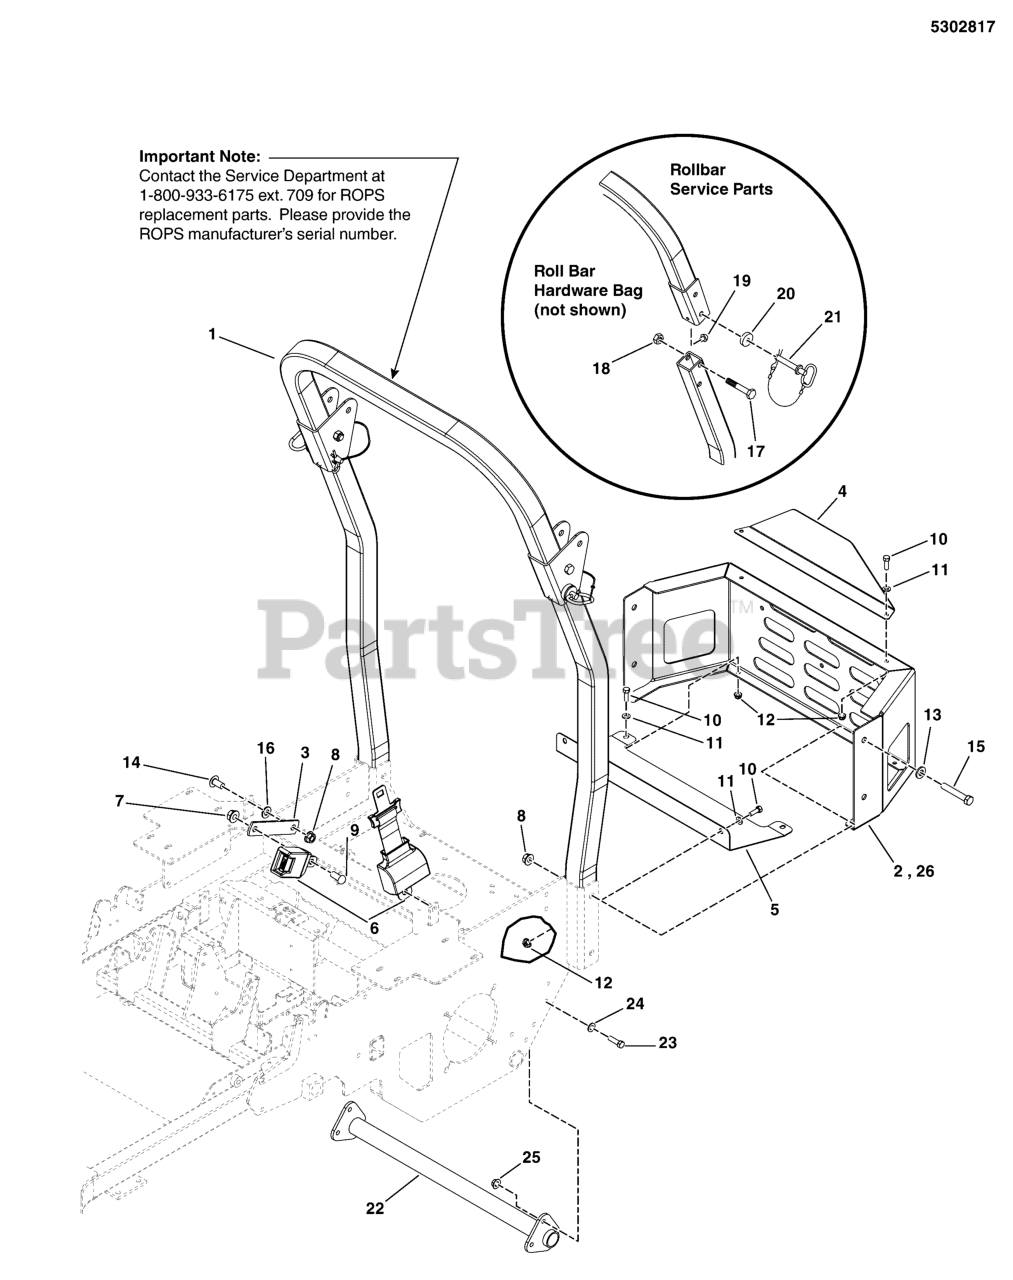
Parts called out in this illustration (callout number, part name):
1	ROPS (Call 1-800-933-6175 ext. 2193 if replacing a ROPS)
2	WELD, PLATE, BUMPER - RED
3	EXTENSION, SEAT BELT - BLK
4	PLATE, CARB. SHIELD - RED
5	PLATE, HEAT SHIELD - BLK
6	SEAT BELT, RETRACTING - ASSM
7	NUT, Hex, Nylon Lock, 1/2-20
8	NUT, Hex Flange, Nylock, 1/2-13
9	SCREW, 1/2-13 X 1.00, SHCS
10	BOLT, 5/16-18 X 3/4 GD5
11	WASHER, 5/16" SAE
12	NUT, 5/16-18 HEX NYLOCK FLANGE
13	WASHER, 1/2 SAE
14	BOLT, 1/2-20 X 1-1/4" GD5 CZ
15	BOLT, 1/2-13 X 3" GD5 CZ
16	WASHER, 1/2 GD9 YZ
17	* BOLT (SV)
18	* NUT (SV)
19	RUBBER BUMPER (SV)
20	RUBBER WASHER (SV)
21	PIN, HITCH, BLACK W/ PLASTIC LANYARD (SV)
22	WELD, BRAKE BUMPER - RED
23	BOLT, 3/8-16 X 1-1/4" GD5 CZ
24	WASHER, 3/8 SAE
25	NUT, 3/8-16 HEX SERRATED FLANGE
26	WELD, PLATE BUMPER - RED
